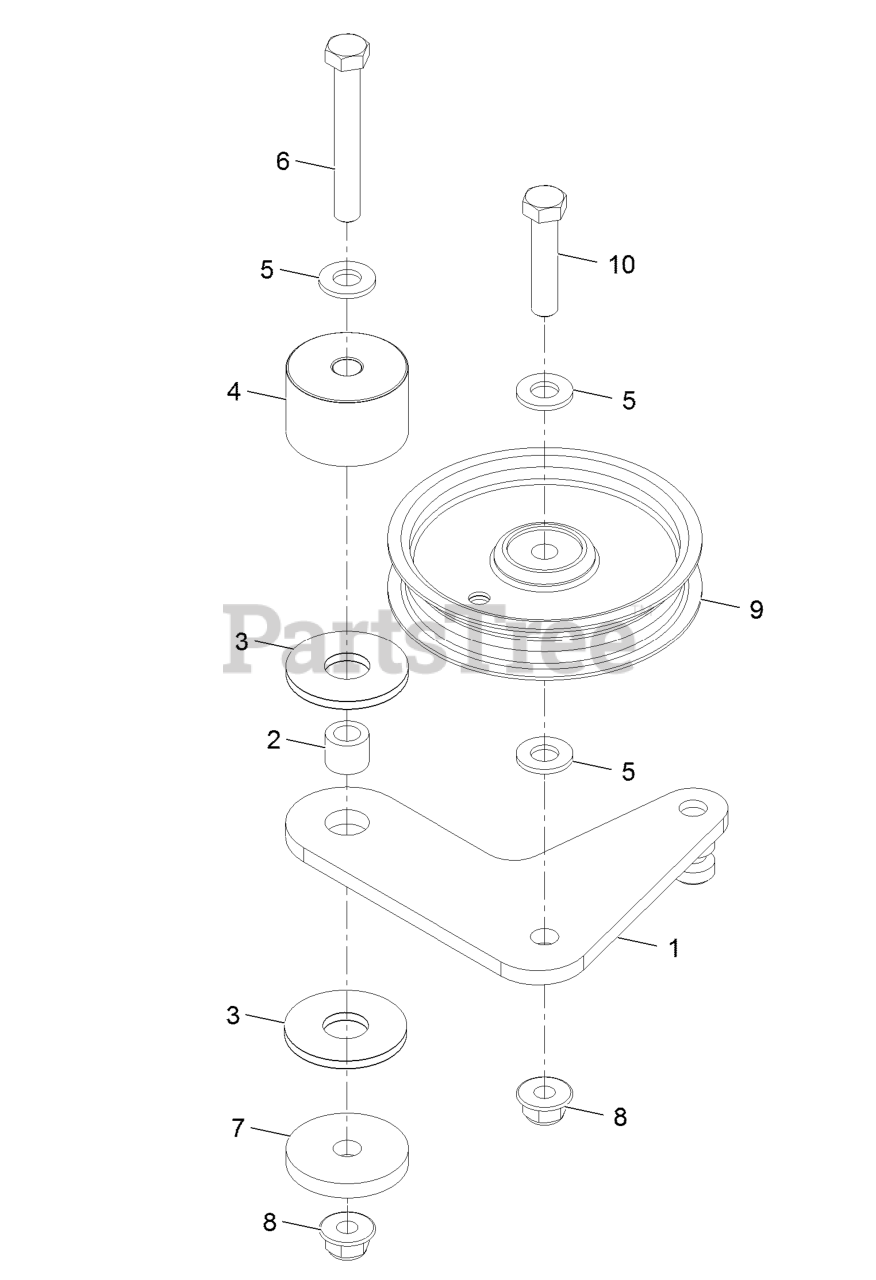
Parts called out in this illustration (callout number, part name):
1	PLATE-IDLER
2	BUSHING-LEVER, LIFT
3	WASHER-FRICTION, COMPOSIT
4	HUB, IDLER
5	WASHER-FLAT
6	SCREW-HH
7	WASHER-PLAIN
8	NUT-HF, NI
9	PULLEY-IDLER
10	SCREW-HH
